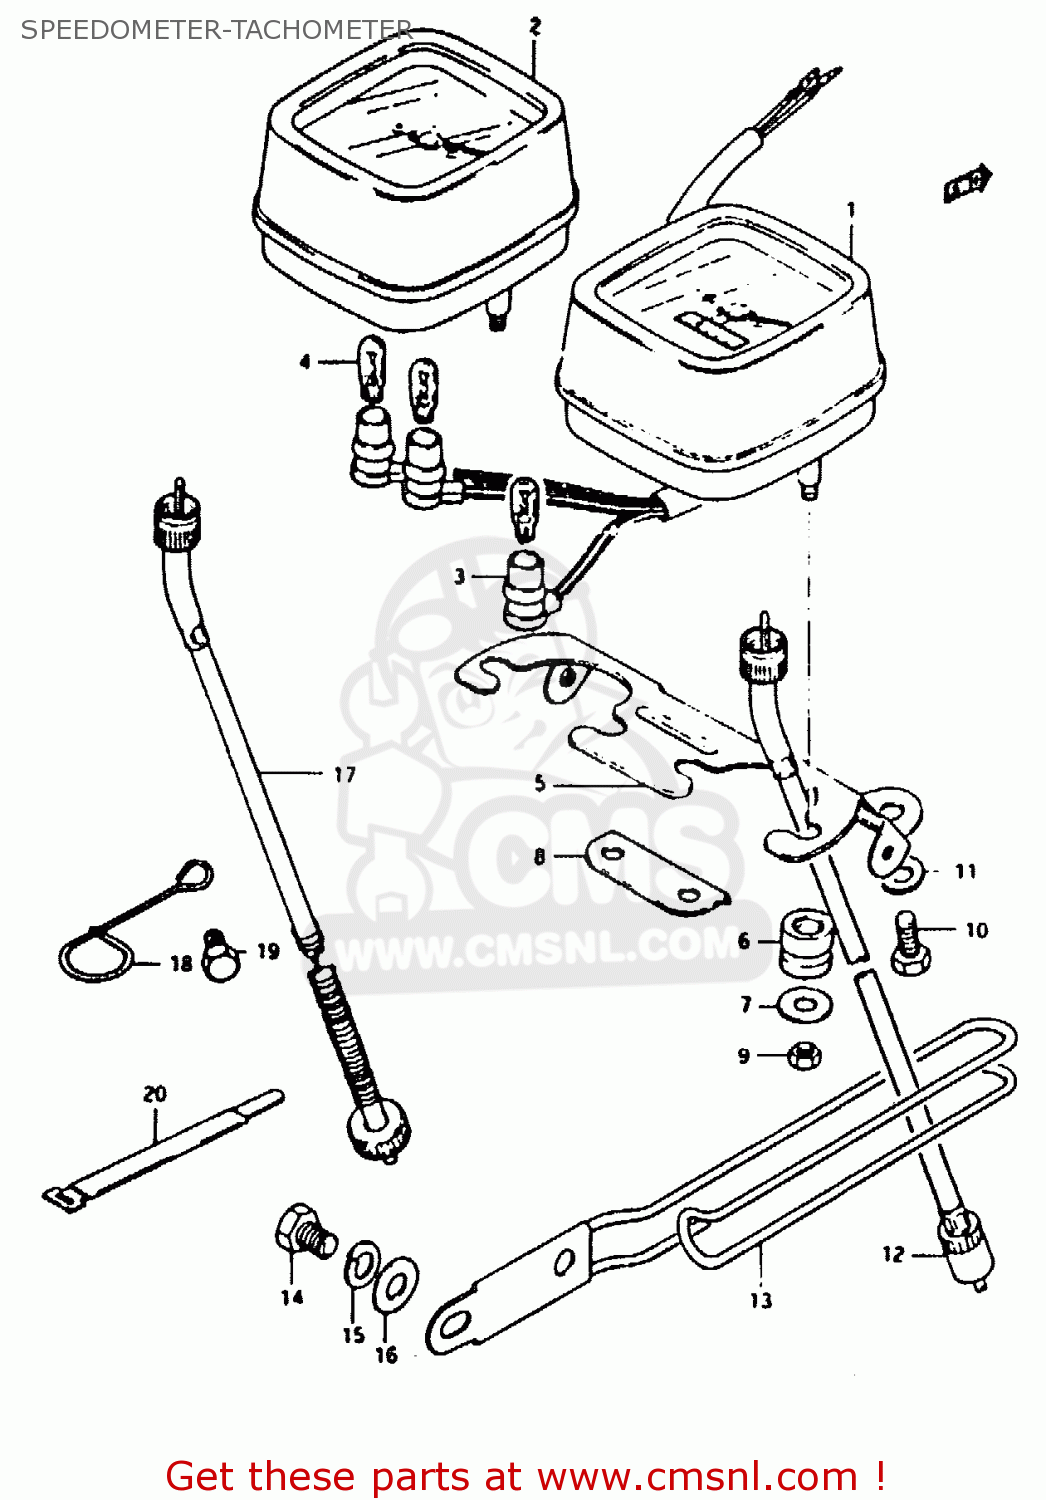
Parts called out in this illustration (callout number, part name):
1	SPEEDOMETER (KILO)
2	METER,TACHOMETER
3	SOCKET
4	BULB(6V1.7W,STANLEY,A61A)
5	BRACKET,SPEEDOMETER
6	CUSHION
7	WASHER,METER
8	PLATE,METER CONNECTING
9	NUT
10	BOLT, UPPER
11	WASHER
12	CABLE ASSEMBLY,SPEEDOMETER
13	GUIDE,CABLE
14	BOLT 8X12
15	LOCK WASHER
16	WASHER
17	CABLE, TACHOMETER
18	CLIP
19	BOLT
20	CLAMP
